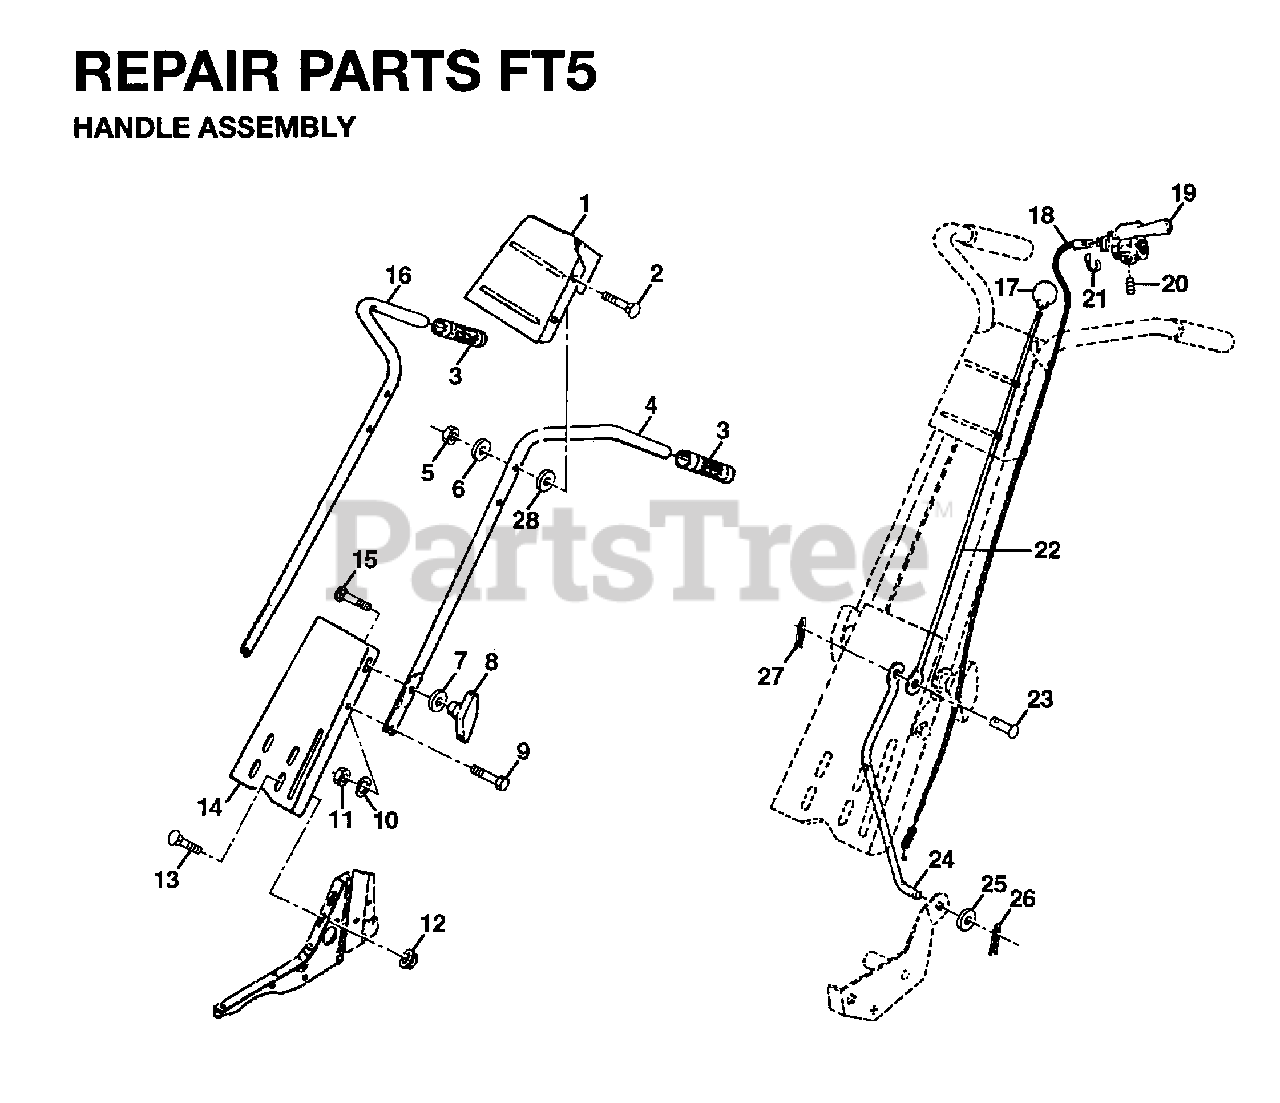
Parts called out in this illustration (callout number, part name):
5	LOCKNUT
6	WASHER - 15X7.3X1.6
7	WASHER
8	HANDLE KNOB
10	LOCKWASHER
12	LOCKNUT
13	BOLT
17	KNOB T (3/8 HOLE)
21	RETAINING RING
25	WASHER
26	COTTER PIN
27	COTTER PIN
28	WASHER
